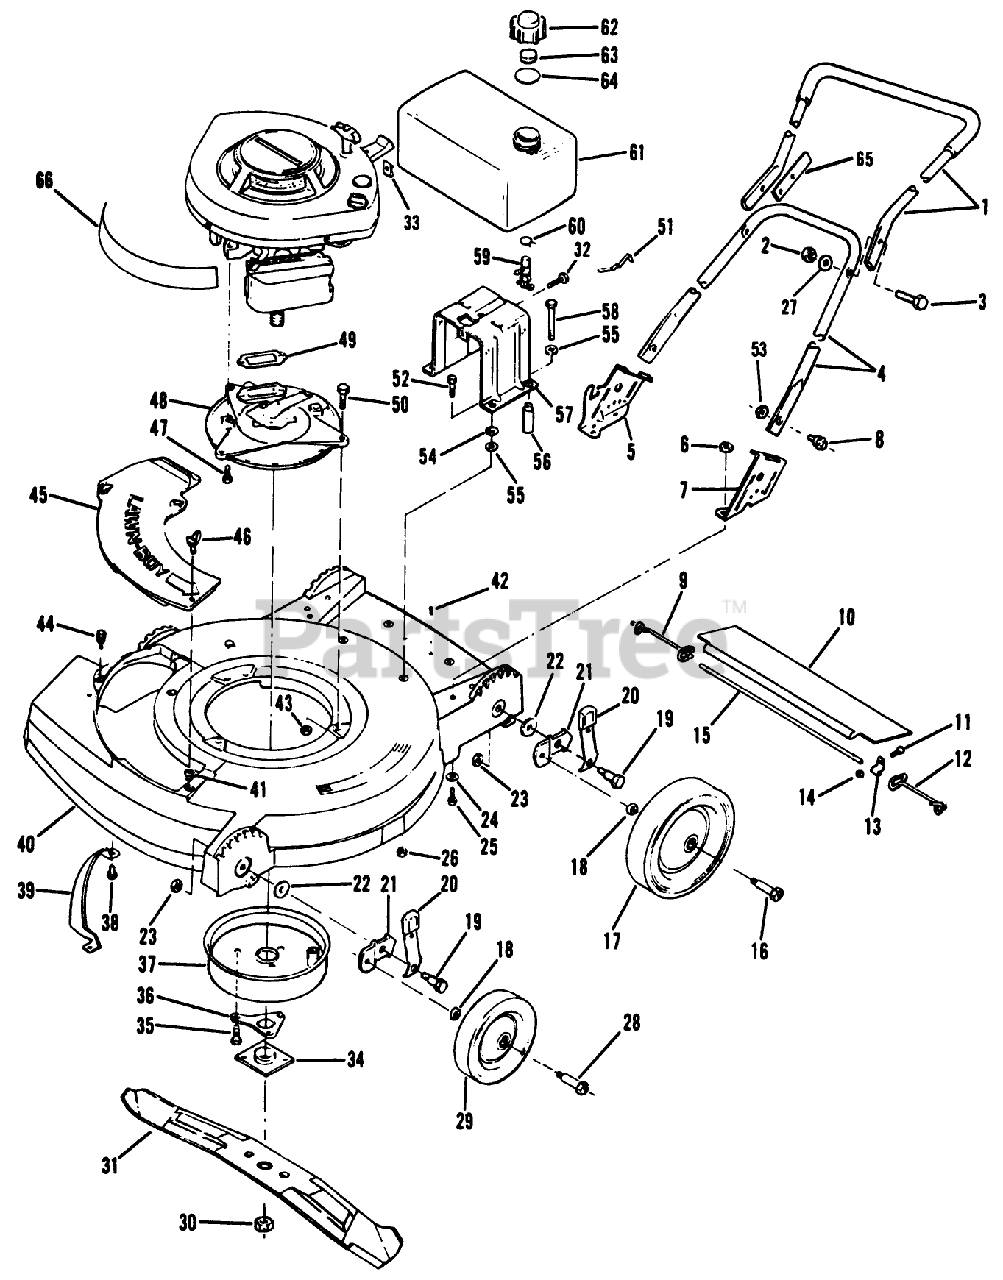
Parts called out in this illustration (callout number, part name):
1	Top Handle Grip Assy
2	LOCKNUT E
4	Handle Bottom
6	NUT-LOCK F
8	BOLT
9	SPRING;TRAILING SHIELD RH
10	T/SHIELD GEAUGA
12	SPRIG T/SHLD ASOC
13	CLAMP ROD KMC
14	LOCKNUT E
15	ROD 21" ADVANCE
16	BOLT-SHOULDER
18	WASHER WROUGHT
22	WASHER
23	LOCKNUT
24	WASHER
26	LOCKNUT E
27	WASHER-CURVED
30	NUT-BLADE
32	SCREW S
33	NUT-SPEED
34	PLATE AND COLLAR ASM
35	SCREW
36	SUPPORT F
37	MUFFLER COVER F
39	BAR-TOE
43	NUT-LOCK F
46	WING SCREW LAWRE
47	SCREW V
50	SCREW
51	SPRING
53	NUT-JAM, LOCKING
55	WASHER
58	BOLT PIONEER
59	VALVE&SCREEN SM
60	CLAMP - HOSE S
63	GASKET S
64	BAFFLE - FOAM SM
